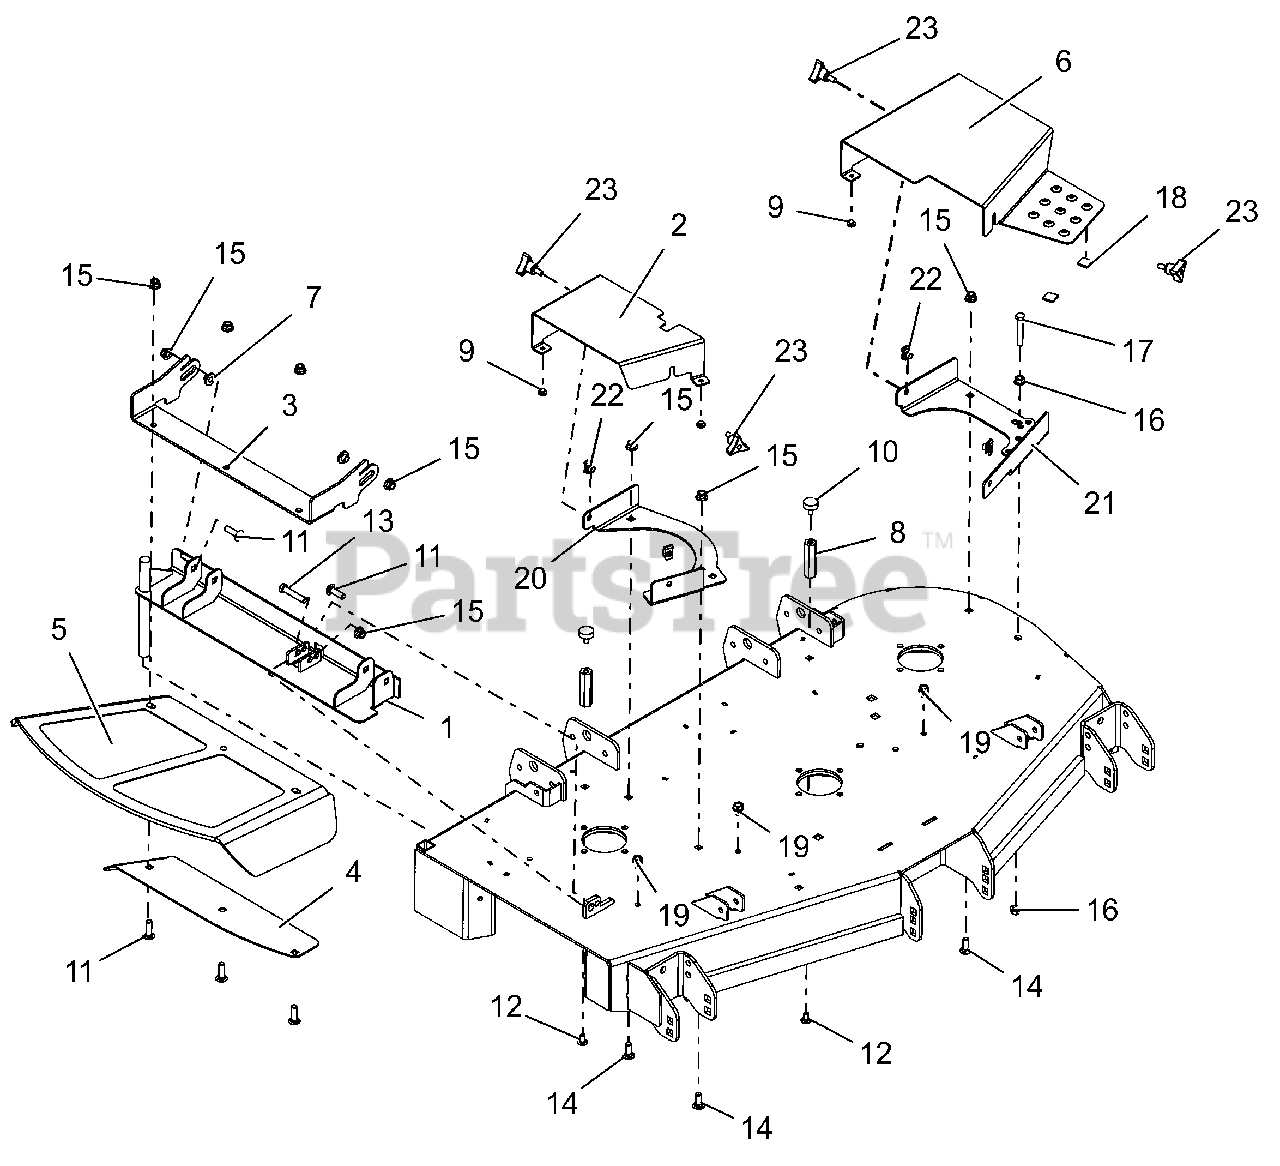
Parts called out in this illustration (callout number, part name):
1	48-60 DISCH CHT MTG WMT W/SAFE
2	PT148-152 DECK RH BELT GRD-RED
3	48-60" CHUTE MTG BRKT - RED
4	48-60 DISCH CHUTE CLMP PLT-RED
5	CHUTE,48-60" FRMD RUBBER DISCH
6	PT100 DECK LH BELT GUARD - RED
7	BSHG-FLG .385X.500X.875X.406
8	NUT, COUPLING .31-18 2.75 LG
9	BUMPER GROMMET
10	BUMPER, RUBBER
11	@BLT-RHDSSQNK .38-16X1.25 G5YZ
12	BLT-RDHDSQSHNK.31-18X.62 YZ-LK
13	@BLT-HEX .38-16X2.00 GR5 YWZC
14	@BLT-RDHDSQNK .38-16X1.00 G5YZ
15	@NUT-LK-NYL-FLG .38-16 YWZC
16	@NUT-SPNLK-FLG .375-16 YWZC
17	@BLT-HEX .38-16X2.25 GR5 YWZC
19	@SCR-TAP .38-16X.50 HWH TR YWZ
20	BRKT, BELT GUARD RH MOUNTING (RED)
21	BRKT, BELT GUARD LH (RED)
22	NUT-CLIP RETAINER 5/16-18X.56
23	KNOB,WING STUD 5/16-18 X .75
